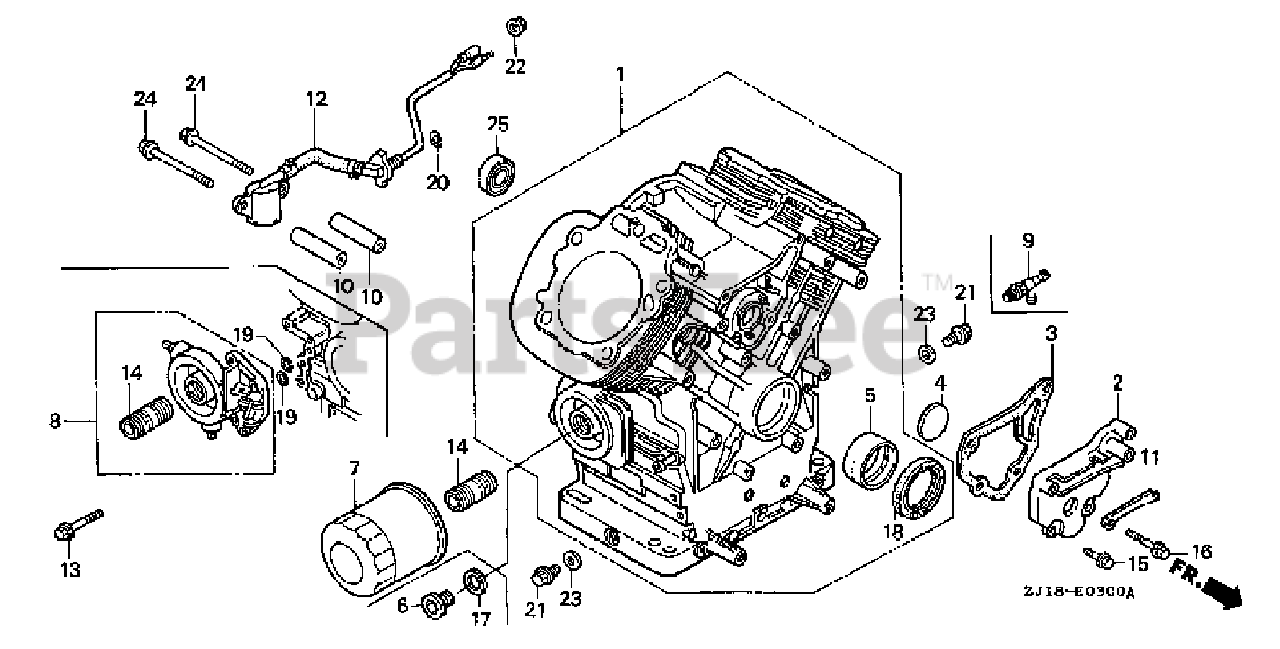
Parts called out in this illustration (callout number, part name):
1	CYLINDER ASSY. (W/O-PUMP)
2	COVER, BREATHER
3	GASKET, BREATHER COVER
4	VALVE, BREATHER
5	BEARING A, MAIN (TO SELECT CORRECT BEARING,
5	BEARING B, MAIN (TO SELECT CORRECT BEARING,
5	BEARING C, MAIN (TO SELECT CORRECT BEARING,
7	FILTER, OIL (FILTECH INC.) (SOLD IN MULTIPLES OF 30)
7	FILTER, OIL (SOLD INDIVIDUALLY)
9	VALVE, DRAIN (14X1.5)
11	CLAMP, WIRE
14	HOLDER, OIL FILTER
15	BOLT, FLANGE (6X16)
16	BOLT, FLANGE (6X32)
18	OIL SEAL (38X58X11)
21	BOLT, DRAIN PLUG (14MM)
23	WASHER, DRAIN PLUG (14MM)
25	BEARING, RADIAL BALL (6003)
